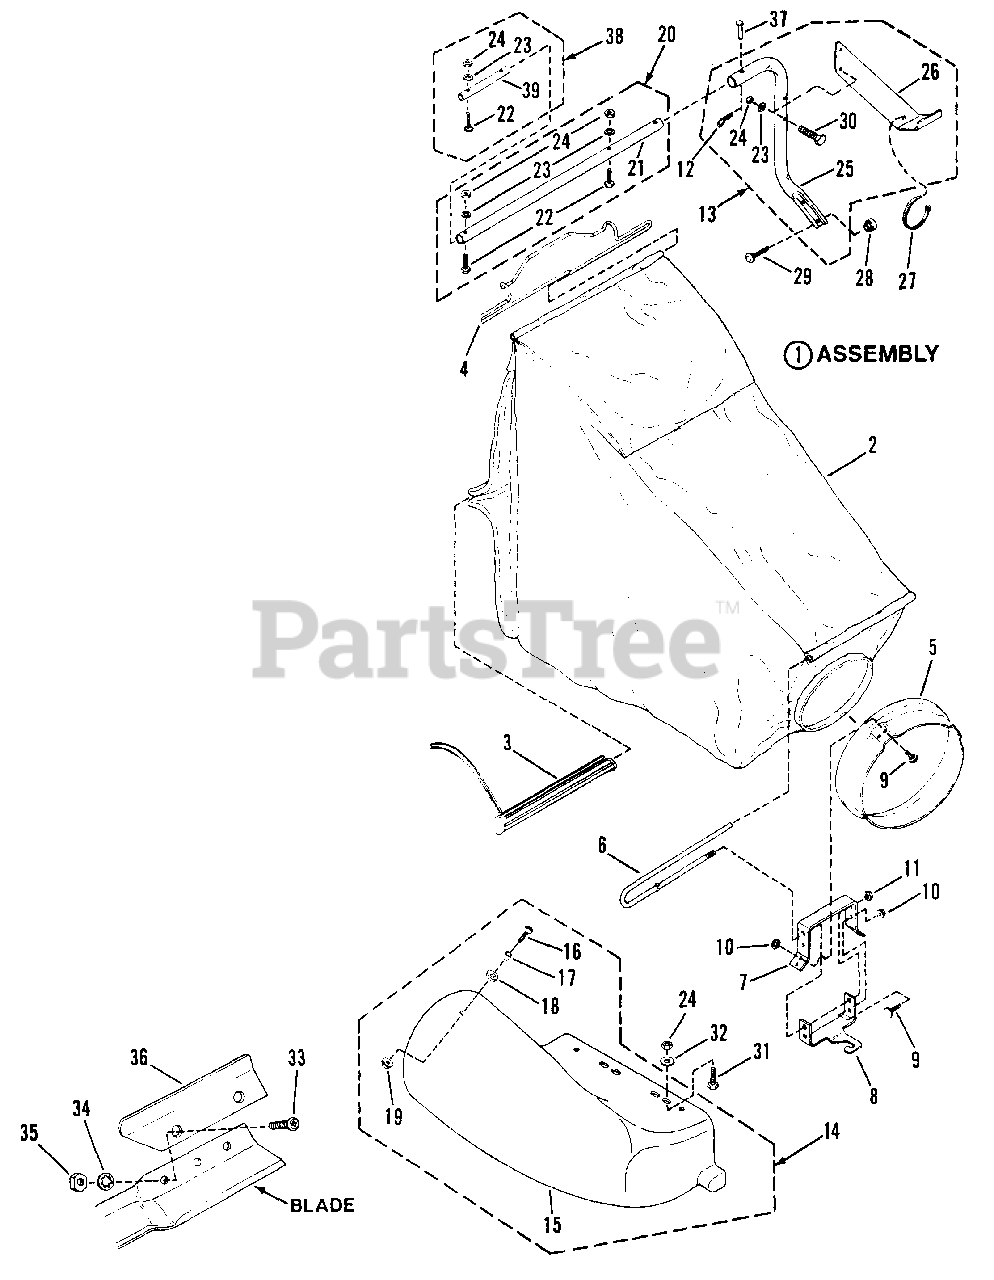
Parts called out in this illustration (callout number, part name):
1	BAG ASSM'Y., Grass
2	BAG, Grass
3	SLIDER, Grass Bag
4	WIRE, Support, Bag, Rear
5	RING, Connector
6	WIRE, Bag, Front
7	CONNECTOR, Handle
8	LATCH, Connector
9	BOLT, 1/4-20 x 5/8" F.H.C.
10	NUT, 1/4-20 Flange Lock
11	NUT, 3/8-24 Hex, Ctr. Lock
12	PIN, Hair, 1/4
13	BRACKET ASSM'Y., Rear Bag Support
14	ADAPTER ASSM'Y., Bag
15	CHUTE ASSEMBLY
16	SCREW, 1/4-20 x 3/4" Slotted Rnd. Hd. Machine
17	SPACER
18	WASHER, 5/16" I.D., 1" O.D.
19	NUT, 1/4-20 Hex Flng. Top Lock
20	SUPPORT ASSM'Y., Bag, Rear
21	TUBE, Support, Rear Bag
22	BOLT, 1/4-28 x 1-1/4"
23	WASHER, 1/4 Int. T. Lock
24	NUT, 1/4-28 Hex
25	SUPPORT, Rear Bag
26	BRACKET, Support
27	CABLE-TIE
28	ROLLER
29	BOLT, 5/16-18 x 2-1/2" Carriage
30	SCREW, 1/4-28 x 1-3/8" H.H.C.
31	SCREW, 1/4-28 x 3/4" H.H.C.
32	WASHER, 1/4 Flat
33	SCREW,5/16-24 x 21/32" Mach.
34	WASHER, 5/16 Int. T. Lock
35	NUT, 5/16-24 Hex
36	AIR-LIFT
37	PIN, 1/4 x 1-1/8" Clevis
38	EXTENSION ASSM'Y.
39	TUBE, Extension Assm'y.
